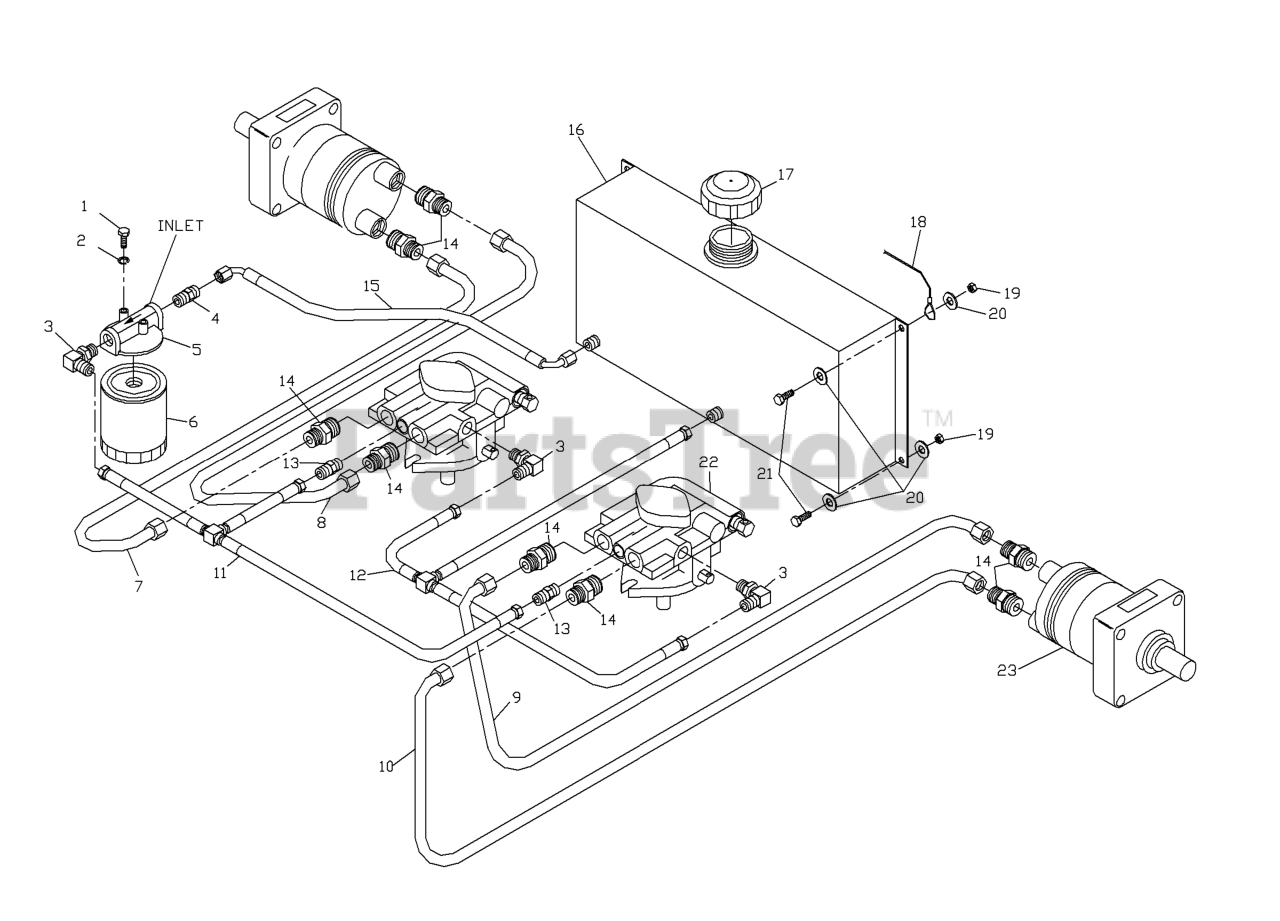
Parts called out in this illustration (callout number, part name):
1	HCS 1/4C X 5/8
2	LOCKWASHER 1/4"
3	ELBOW, F6801-6-6-0 90 DEGREE
4	STRAIGHT FITG
5	FILTER HEAD
6	HYDRAULIC OIL FILTER
7	OUTSIDE TUBE, RIGHT
8	INSIDE TUBE, RIGHT
9	INSIDE TUBE, LEFT
10	OUTSIDE TUBE, LEFT
11	SUCTION TEE ASSEMBLY
12	RETURN TEE ASSEMBLY
13	FITTING, STRAIGHT F6400-6-4-0
14	FITTING, STRAIGHT F6400-8-8-0
16	TANK, HYDRAULIC
17	HYDRAULIC CAP
18	SEAT LANYARD
19	NUT 1/4C CENTER LOCK
20	WASHER 1/4 FLAT
21	HCS 1/4 X 1
23	WHEEL MOTOR
